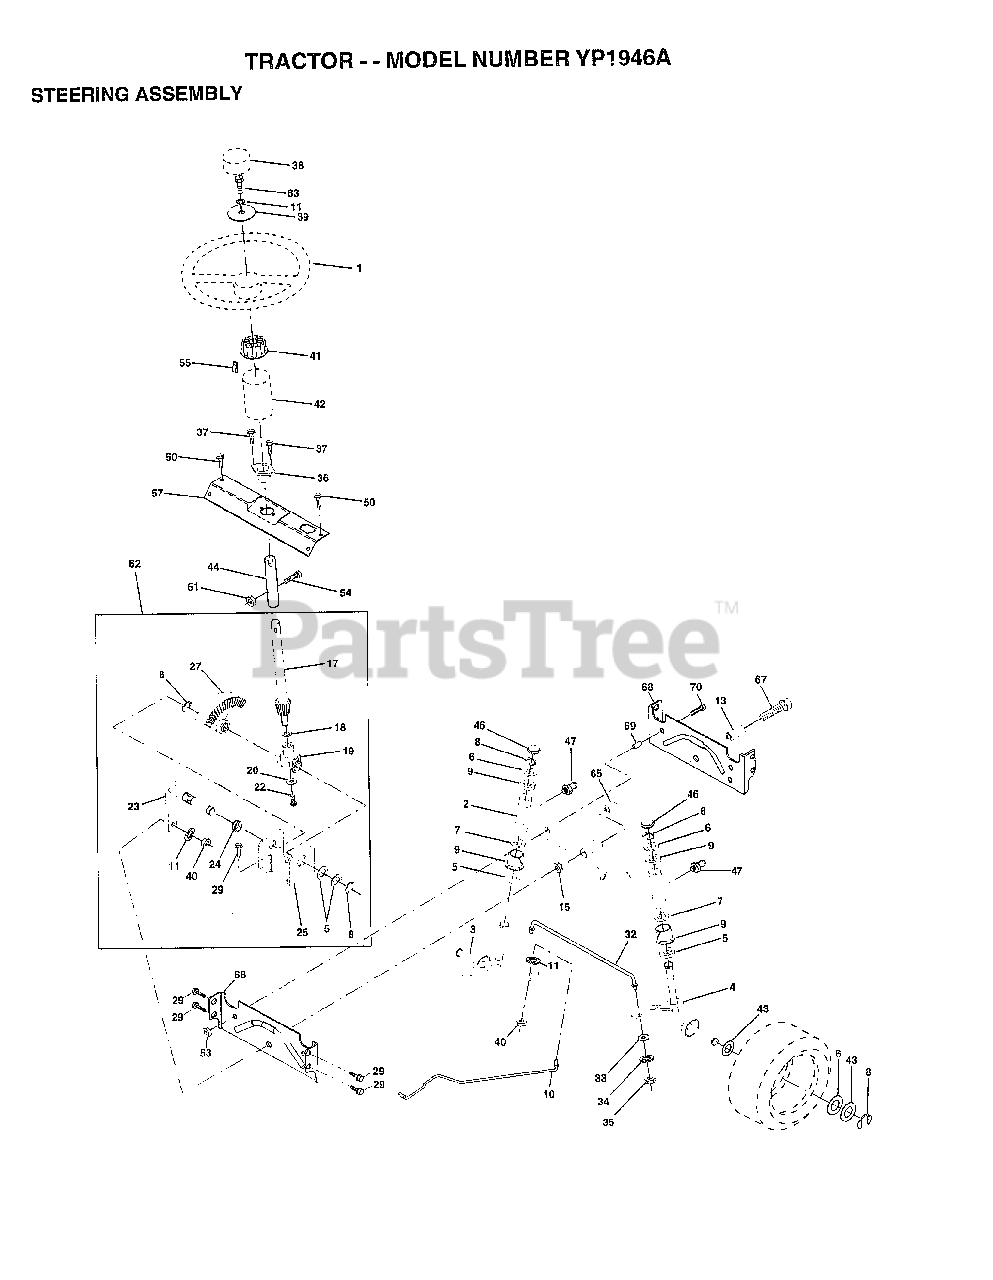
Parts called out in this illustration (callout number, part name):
2	AXLE ASM
3	SPINDLE.ASM.LH
4	"SPINDLE ASM,RH"
5	WASHER .T
6	WASHER
7	WASHER
8	RING
9	COL. SRTG. BEAR.
10	DRAGLINK-STAMPED
11	LOCKWASHER
13	BEARING AXLE
15	"NUT-LOC,FLANGE LT"
17	SHAFT ASM STEERIN
18	THRUST WASHER
19	SUPPORT.SHAFT
22	SCREW HEX SOC1/4-
25	BRKT-STEERING
27	GEAR SECTOR
29	SCREW
32	ROD.TIE.19.75
33	WASHER M
34	LOCKWASHER
35	NUT.LOCK.5/16-24
36	BUSHING.STR.623
37	"SCREW-TT,10-32 FL"
38	"INSERT,STR WHEEL"
39	WASHER T
40	GRIPCO NUT
41	ADAPTER LT
42	BOOT SHAFT STEER
43	WASHER
44	SHAFT EXT STEERIN
46	CAP
47	ZERK M
50	SCREW HEX CRT
51	NUT
54	BOLT
55	CLIP TINNERMAN
57	SUPPORT SHAFT STR
62	KIT STEERING ASM
63	BOLT
65	SPACER AXLE
66	"BEARING-ARM,PITMA"
67	BOLT
68	BRACE AXLE
69	"SPACER BRCAE,AXLE"
70	BOLT.HEX.3/8-16X2
